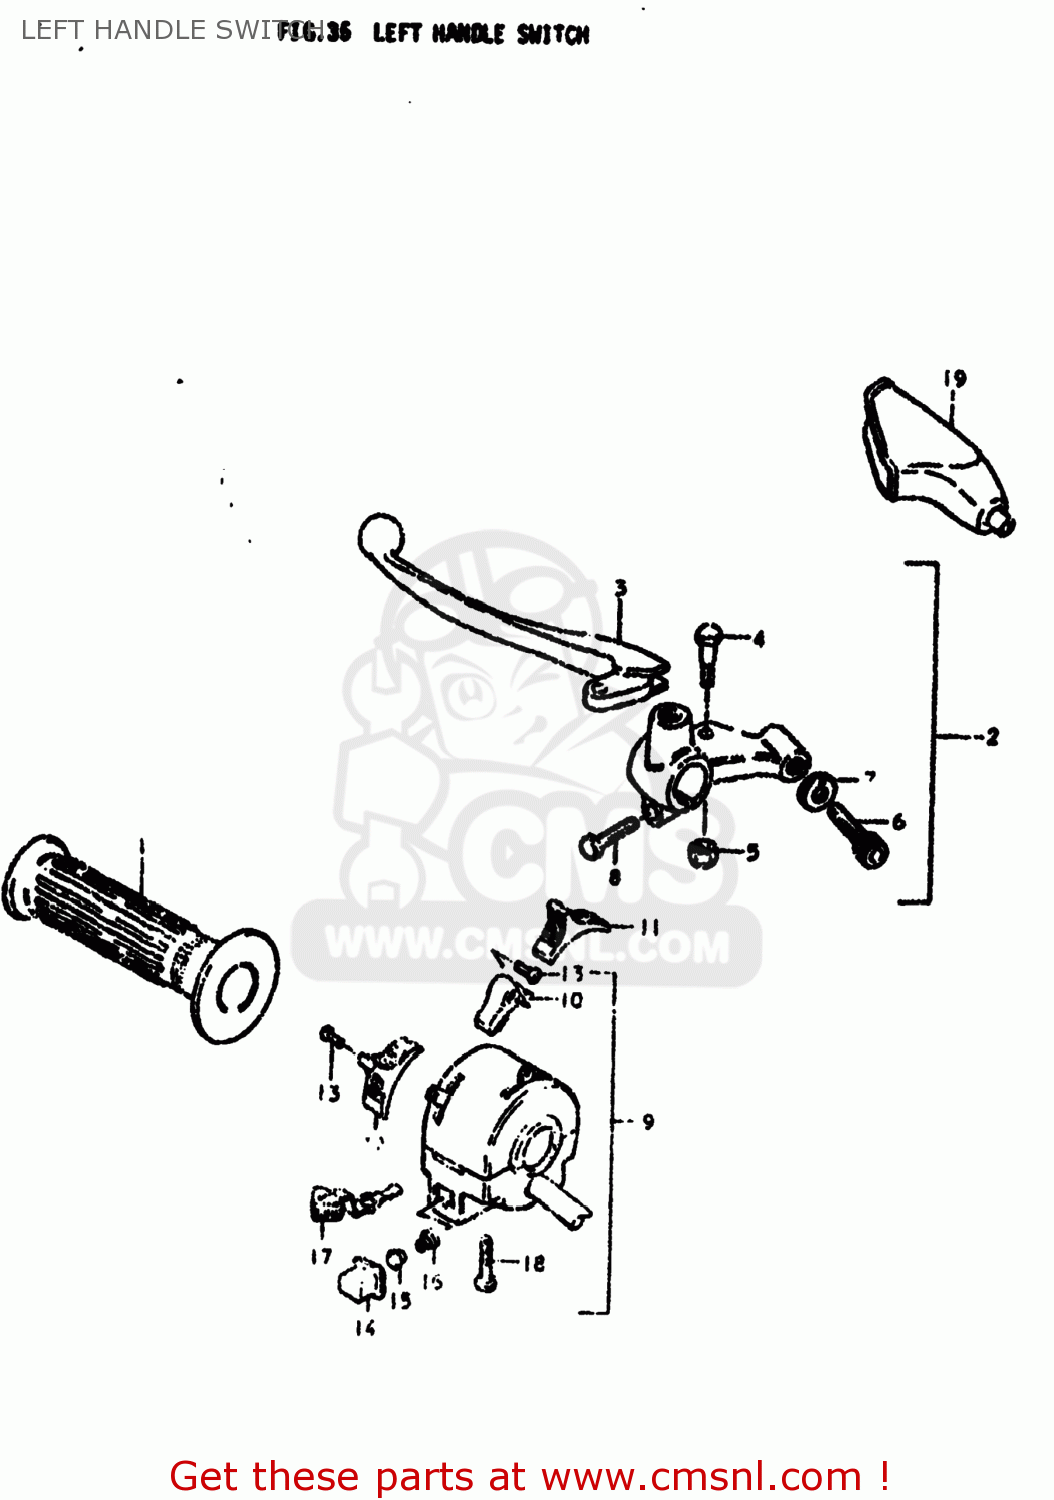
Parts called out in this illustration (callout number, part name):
1	GRIP,L
2	LEVER ASSY,CLUTCH
3	LEVER,CLUTCH
4	BOLT,LEVER
5	NUT 6MM
6	ADJUSTER,CABLE
7	NUT,CABLE ADJUSTER
8	BOLT
9	SWITCH ASSEMBLY,HANDLE,LEFT
10	KNOB,STOP
11	KNOB,LIGHTING SWITCH
12	KNOB,DIMMER SWITCH
13	SCREW
14	BUTTON,HORN
15	CONTACT
16	SPRING
17	KNOB,TURNSIGNAL
18	SCREW
19	COVER,CLUTCH LEVER
